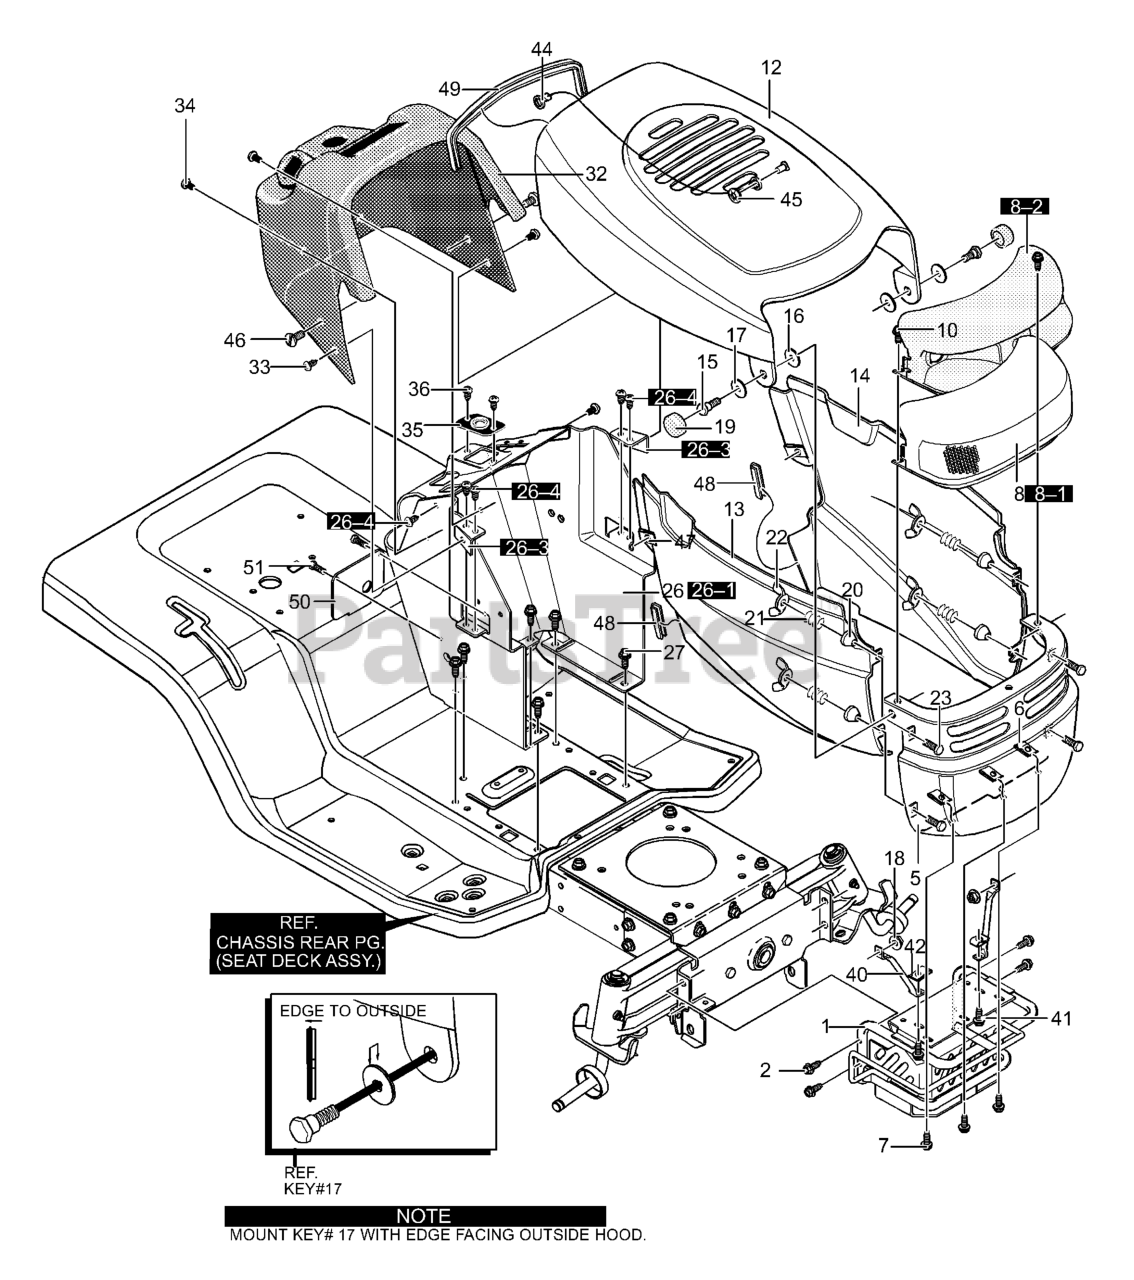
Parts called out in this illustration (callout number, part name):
1	ASSEMBLY, BUMP/GRILLE
2	SCRW 5/16-18X1.50
6	NUT, "J" TINNERMAN
7	SCRW,1/4-20X .63
8	ASM., LENS & REFLECTOR
8-2	REFLECTOR
10	SCREW 1/4-14X.50
12	ASM., WELD HOOD H26
13	PANEL, SIDE RH
14	PANEL, SIDE LH
16	WASHER, PLASTIC BLACK
17	PIVOT BASE GREY
18	NUT, 3/8-16
19	PIVOT CAP GREY
20	QUICK RELEASE-CAM
21	SPRING, COMP
22	NUT, WING 1/4-20
23	SCREW, 1/4-20X1.25
26	ASM., CONSOLE
26-1	CONSOLE
26-2	BRACKET, LEFT
26-3	BRACKET, RIGHT
27	SCRW 5/16-18X.75
32	DASH, H26 GREY
33	SCREW, 10-24X.50
34	SCREW, 10-24X.50
35	STEERING BRACKET
36	SCREW 1/4-14X.50
40	STRUT, H26 GRILLE
41	SCREW, 1/4-20X .63
42	SPEED NUT
44	LANYARD, H26 HOOD
45	PUSHNUT
46	SCREW, 1/4-20X0.63
47	NUT, "J" TINNERMAN
48	TRIM PIECE PLASTIC GREY
49	TRIM PIECE PLASTIC GREY
50	ACCESS PANEL, W/O SLOT
51	SCREW, 10-24X.50
